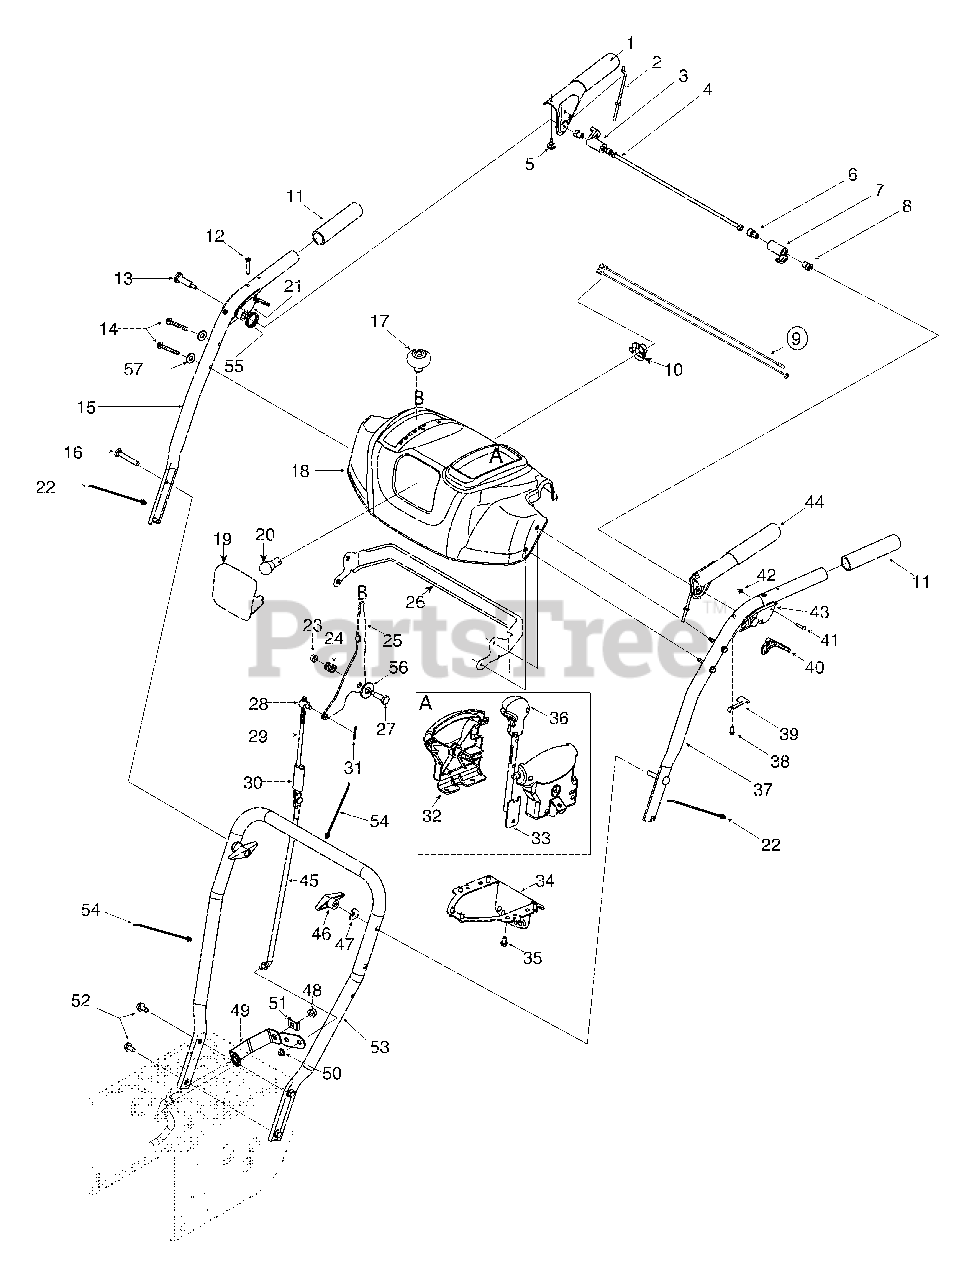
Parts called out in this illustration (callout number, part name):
1	Handle Engagement Assembly RH
2	Cable Z Fitting
3	Lock Plate
4	Pivot Rod
5	Rubber Bumper
6	Screw, 1/4-20 x.375
7	Clutch Lock Cam
8	Shoulder Nut, 1/4-20
9	Wire Harness
10	Light Socket
11	Handle Grip
12	Screw, #10-24 x 0.375
13	Shoulder Screw,1 /4-20 x 1.345
14	Screw, 1/4-20 x 1.750
16	Carriage Screw, 5/16-18 x 2.25
17	Shift Knob
18	Handle Panel
19	Lens
20	Lamp
21	Handle Clutch Lock - RH
22	Cable Tie
23	Flange Lock Nut, 1/4-20
24	Compression Spring
28	Ferrule
29	Upper Shift Rod
30	Shift Rod Connector
31	Hairpin Clip
32	Kit, Chute Control Housing
33	Kit, Lever Tube Knob & Cable
35	Hi-Lo Screw, 1/4-15 x 0.5
36	Kit, 4-Way Knob
38	Screw, #8-16 x 0.50
39	Clutch Lock Spring
40	Steering Control
41	Pin, 3/16
42	E Ring
43	Handle Clutch Lock - LH
44	Handle Engagement Assembly LH
45	Lower Shift Control Rod
46	Handle Knob Assembly
47	Saddle Washer
48	Flange Lock Nut, 5/16-18
49	Shift Arm
50	Speed Nut
51	Shift Bracket Spacer
52	AB Screw, 5/16-12 x 0.75
54	Cable Tie
55	Torsion Spring
56	Flat Washer
57	Washer, Flat,.25 x.630 x.0515
